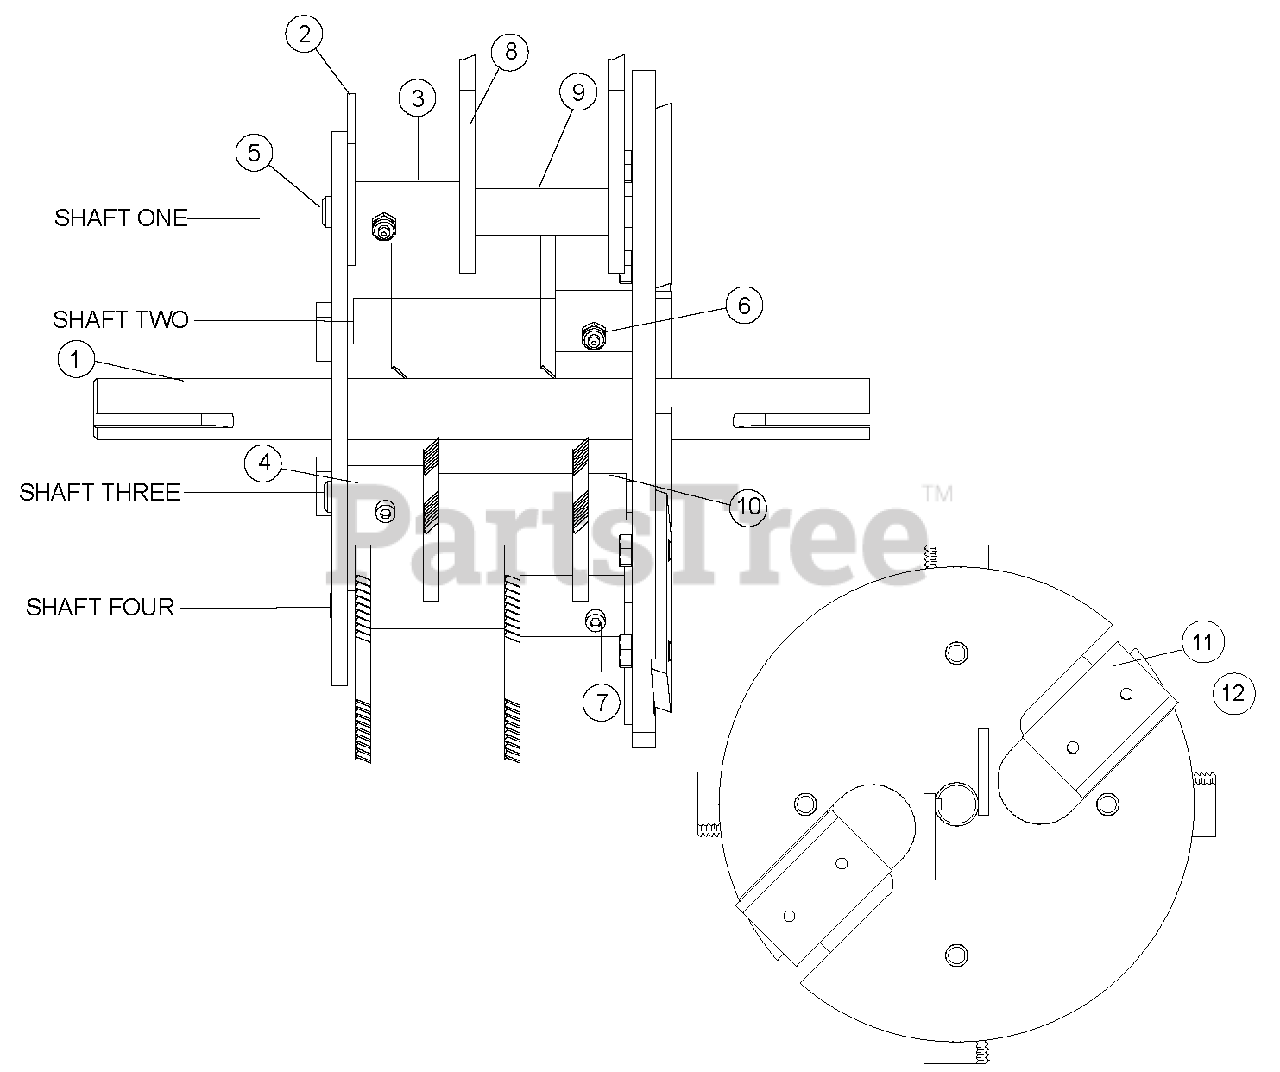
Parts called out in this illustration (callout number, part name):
1	WELDMENT, NARROW ROTOR
2	KNIFE, ROTOR BALANCE
3	SPACER, 1.0 X 1.70 WITH HOLE
4	SPACER, 1.0 X 1.24 WITH HOLE
5	KNIFE SHAFT
6	SCREW, 10-24 X 1-3/8 IN. SKT HD CAP
7	NUT, #10 X 24 NYLOCK
8	SHREDDING KNIFE, RECTANGULAR
9	SPACER, 0.75 X 2.170
10	SPACER, .75 X .62
11	BLADE, TWO EDGE CHIPPER (FOR SERVICE ORDER KIT # 70738, TWO EDGE TOOL STEEL
11	KIT, TWO EDGE BLADE
12	BOLT, 5/16 X 5/8 GR 8
